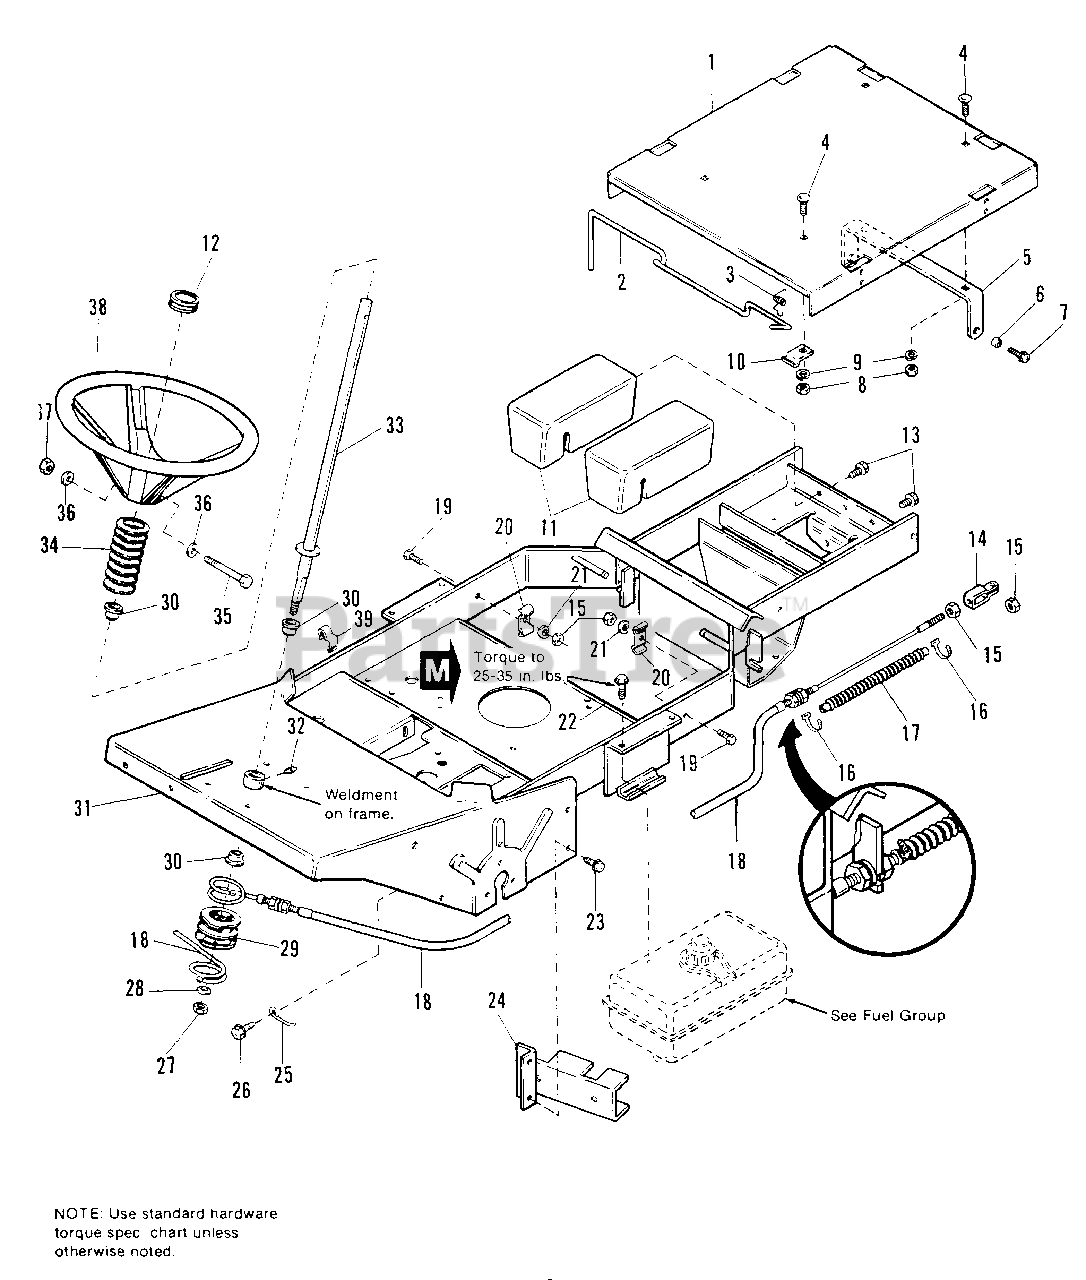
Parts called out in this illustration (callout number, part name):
2	ROD, Latch, Platform
3	SPRING, Torsion, Latch Rod
4	BOLT, Carriage, 5/16-18 x 3/4
5	BRACKET, Pivot, Platform
6	SPACER, Pivot Bracket
7	CAPSCREW, Taptite, 3/8-16 x 3/4
8	NUT, Hex, 5/16-18
9	LOCKWASHER, 5/16
10	CLIP, Latch Rod
11	WEIGHT, Rear
12	CAP, Steering Wheel
13	SCREW, Taptite, 5/16-18 x 3/4
14	CLEVIS, Steering Cable
15	NUT, Hex, 1/4-20
16	TIE, Steering Cable Boot, Self-locking
17	BOOT, Rubber, Steering Cable
18	CABLE, Steering
19	CAPSCREW, 1/4-20 x 1
20	CLAMP, Steering Cable
21	LOCKWASHER, 1/4
22	SCREW, Special, Fuel Tank
23	SCREW, Taptite, 5/16-18 x 1/2
24	SUPPORT ASSY., Fuel Tank
25	RETAINER, Steering Cable
26	CAPSCREW, Taptite, 5/16-18 x 3/4
27	LOCKNUT, 1/2-13, ESNA, Heavy
28	WASHER, 1/2
29	DRUM, Steering Shaft
30	BUSHING, Nylon, Steering Shaft
31	FRAME ASSY. KIT
32	FITTING, Lube
33	STEERING SHAFT ASSY.
34	TUBE, Cover, Steering Shaft
35	CAPSCREW, 5/16-18 x 3-1/2
36	WASHER, 5/16
37	NUT, 5/16-18 Centerlock
38	STEERING WHEEL
39	CLIP, Steering Cable
